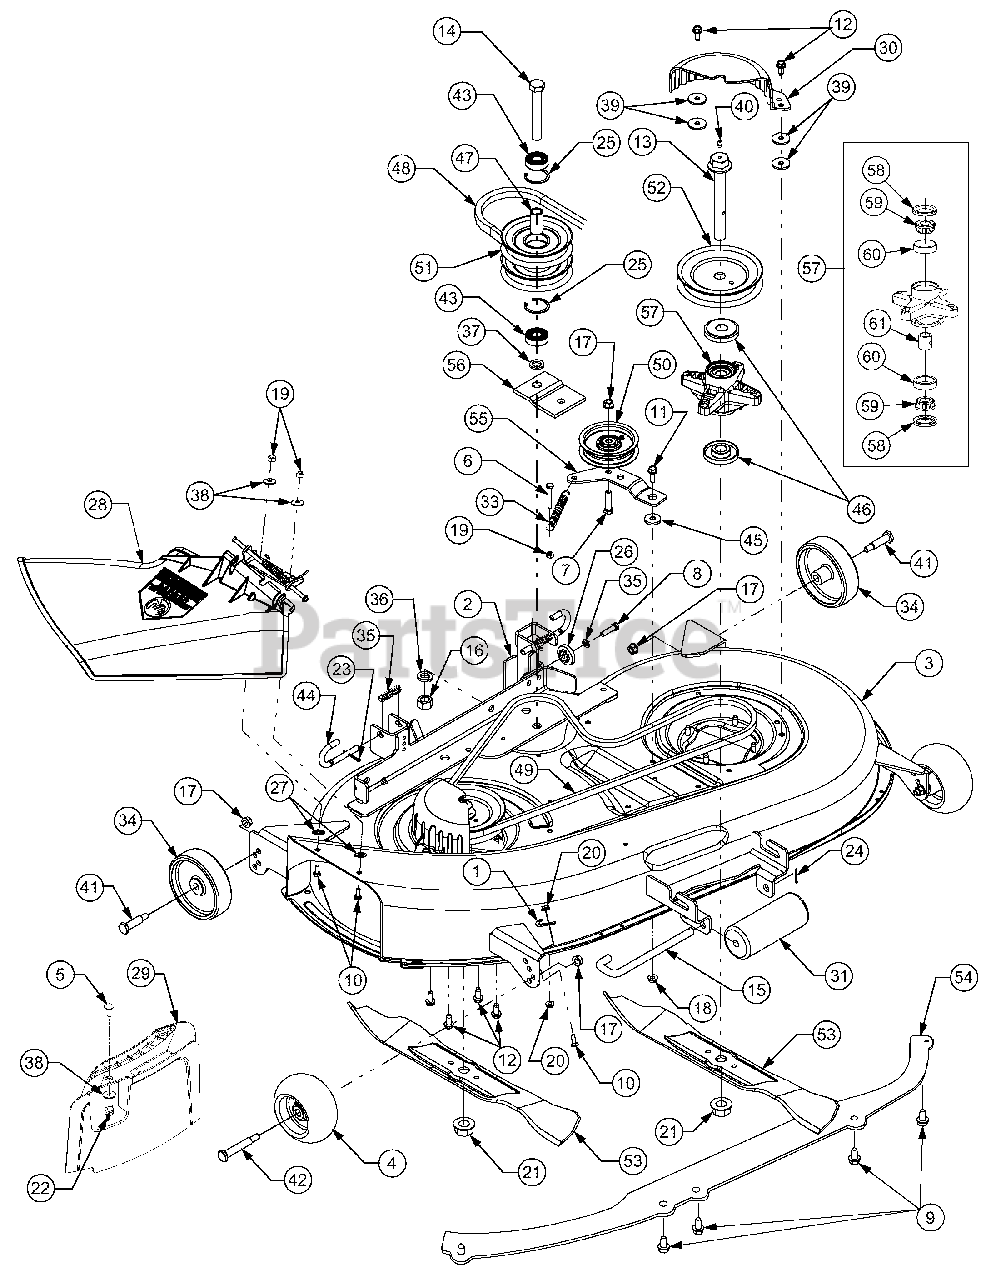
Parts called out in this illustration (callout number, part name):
1	Bracket, Hook, Retainer
4	Wheel, Deck, 5.0 OD w/ Fitting
5	Screw, Carriage, 1/4-20 x .62
6	Screw, Hex Cap, 1/4-20 x 1.75 GR5
7	Screw, Hex Cap, 3/8-16 x 1.5 GR5
8	Screw, 5/16-18, 1.25, Gr5
9	Screw, Hx. Wash, Hd,Tapp 1/4-20 x .5
10	Screw, Hex Cap, 1/4-20, .620, Gr5
11	Screw, Hex Wash., 5/16-18 x .875 GR5
12	Screw, Hex Wash. Hd Tapp 5/16-18 x .75
13	Bolt, Spindle, 3/4-16 x 4.25
14	Screw, Hx. Cap, 5/8-18 x 4.25 GR5
15	Roller Pin 1/2" x 7.31 Lg
16	Nut, Hex, 5/8-18, GR5
17	Nut, Hx. Flange Lock, 3/8-16
18	Nut, Hx. Flange Lock, 5/16-18, Gr5
19	Nut, Hex, 1/4-20, Gr5
20	Nut, Hx. Flange Lock, 1/4-20
21	Nut, Hx. Flange, 3/4-16
22	Nut, Wing, 1/4-20
23	Pin, Cotter, 1/8 x 1.25
24	Pin, Cotter, 3/32 x 1.25
25	Ring, Internal Retaining,
26	Adjustment Gear, Deck
27	Nut, Push, .25 ID x .50 OD
28	Chute Assembly, Side Discharge - Includes the following parts:
29	Plug, Mulch
30	Cover, Belt, Deck
31	Front Roller
32	Spring, Compression, .406 x .531 x
33	Spring, Extension .53 x 4.75
34	Wheel Deck 5.0 x 1.38
35	Washer, Lock, 5/16, Regular Duty
36	Washer, Lock, 5/8
37	Washer, Flat, .641 x 1.0 x .12
38	Washer, Belleville, .265 x .75 x .062
39	Washer, Flat, .330 x 1.25 x .12
40	Fitting, 3/16 Drive Lube
41	Shoulder Screw
42	Shoulder Screw - 1/2 Dia x 2.50 Lg.
43	Bearing, Ball, .625 x 1.57 x .47
44	Rod, Handle, Deck Release .375 Dia
45	Spacer, Shoulder, .625 x .324
46	Spacer, Deck Spindle
47	Spacer, .635 x .88 x 1.72
48	Belt, V, A Sect x 60.06
49	Belt, V, A Sect x 66.90
50	Pulley, Idler, 3.50 Dia.
51	Pulley, Double, 5.0 x 5.0
52	Pulley, Spindle
53	Blade, 21.20 Lg, 3-in-1
57	Spindle Housing Assembly - Includes Ref. Nos. 58 thru 61
58	Seal, Oil, Single Lip
59	Bearing, Cone
60	Cup, Bearing
61	Spacer, Bearing, .780 x 1.000 x
